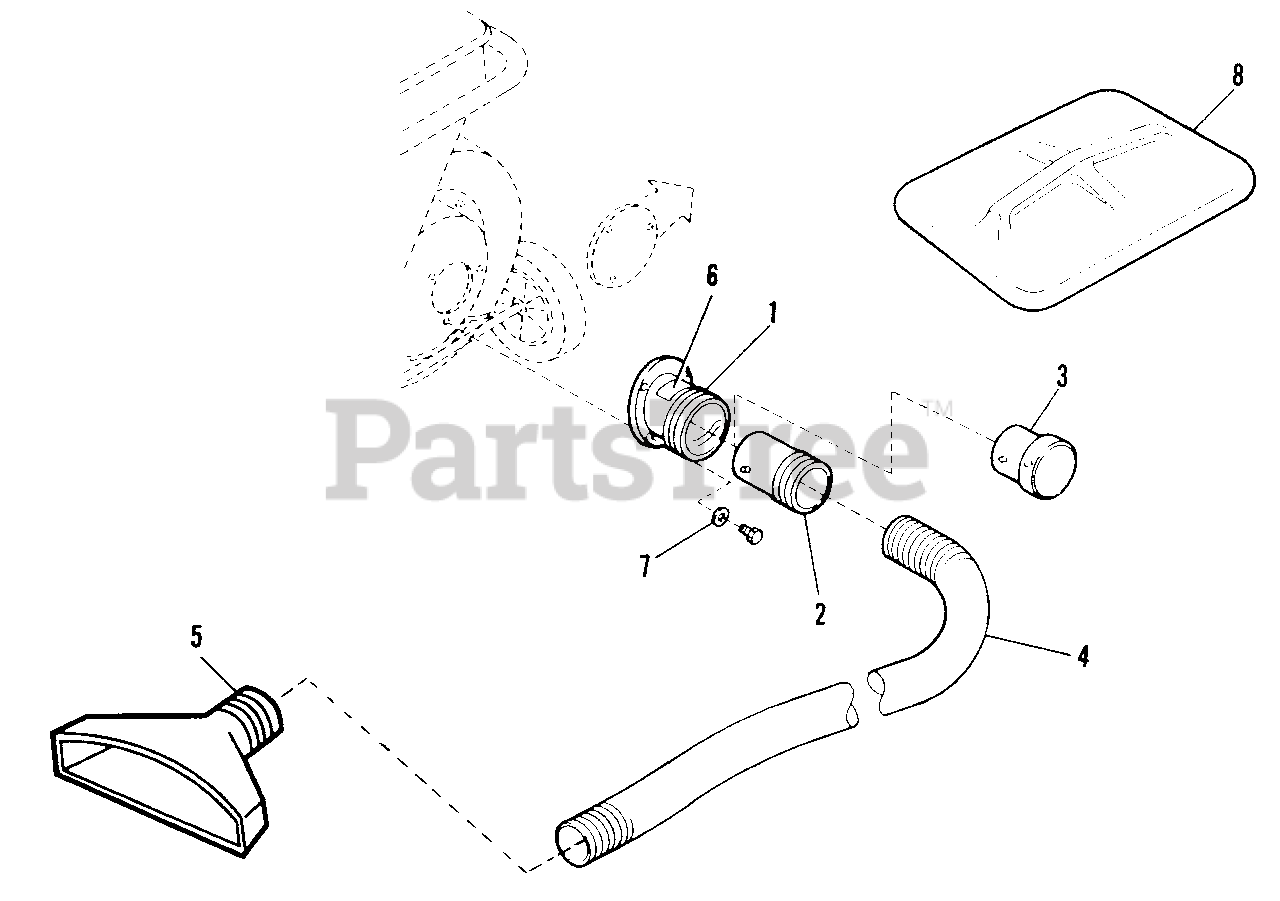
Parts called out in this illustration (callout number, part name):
4	HOSE, 4" x 4" diameter
6	DECAL, Danger
7	WASHER, Flat, 5/16
8	HOPPER LID (Orange)
8	HOPPER LID (Gold)
8	HOPPER LID (Red)
